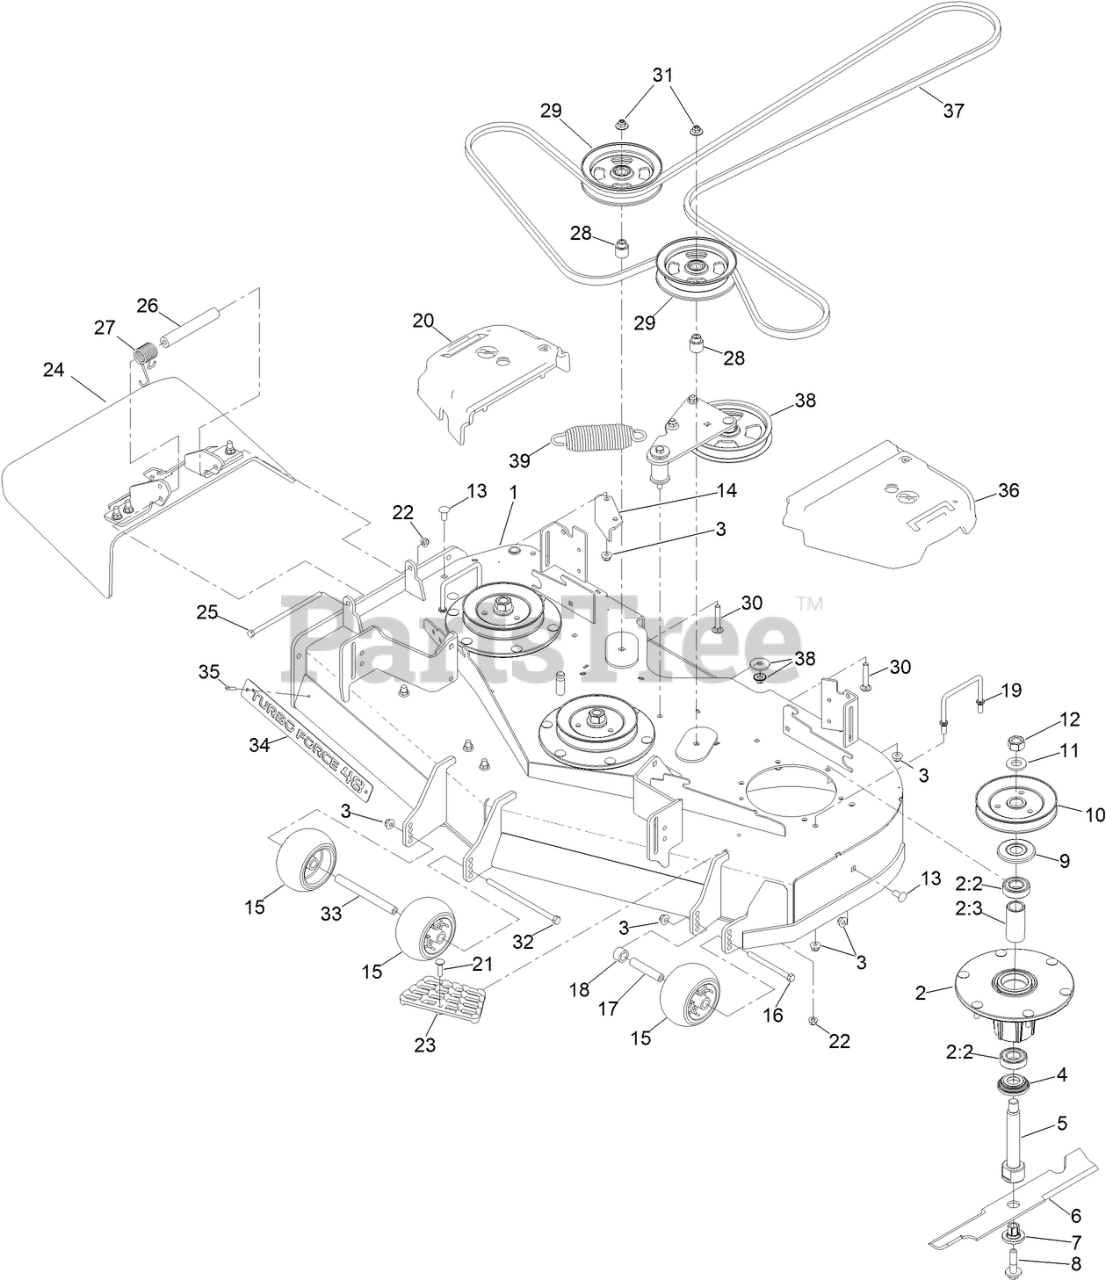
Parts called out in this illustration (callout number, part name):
1	DECK DECAL ASM
2	SPINDLE ASM
2:2	BEARING-BALL
2:3	SPACER-BEARING
3	NUT-HF, NI
4	GUARD-BOTTOM
5	SHAFT-SPINDLE
6	BLADE-16.50 HIGH FLOW
7	BUSHING-HEX
8	SCREW-SEMS
9	GUARD-BEARING, TOP
10	SHEAVE,BLADE DRIVE 5.91
11	WASHER
12	NUT-HEX
13	SCREW-CARR
14	BAFFLE-DISCHARGE
15	ROLLER-SCALP, ANTI
16	SCREW-HH
17	TUBE-SHAFTING
18	TUBE-SPACER
19	WIREFORM-COVER
20	COVER-BELT, RH
21	SCREW-CARR
22	NUT-HF, NI
23	STEP-DECK
24	RUBBER DEFLECTOR ASM
25	SCREW-HH
26	SPACER
27	SPRING-TORSION
28	BUSHING, IDLER
29	PULLEY-IDLER, FLAT
30	SCREW-CARR
31	NUT-FLANGE, NI
32	SCREW-HH
33	SPACER-WHEEL
34	PLATE-TURBO FORCE [BLACK]
35	RIVET-TRIFOLD
36	COVER-BELT, LH
37	BELT-V
38	IDLER ARM ASM
39	SPRING-EXTENSION
